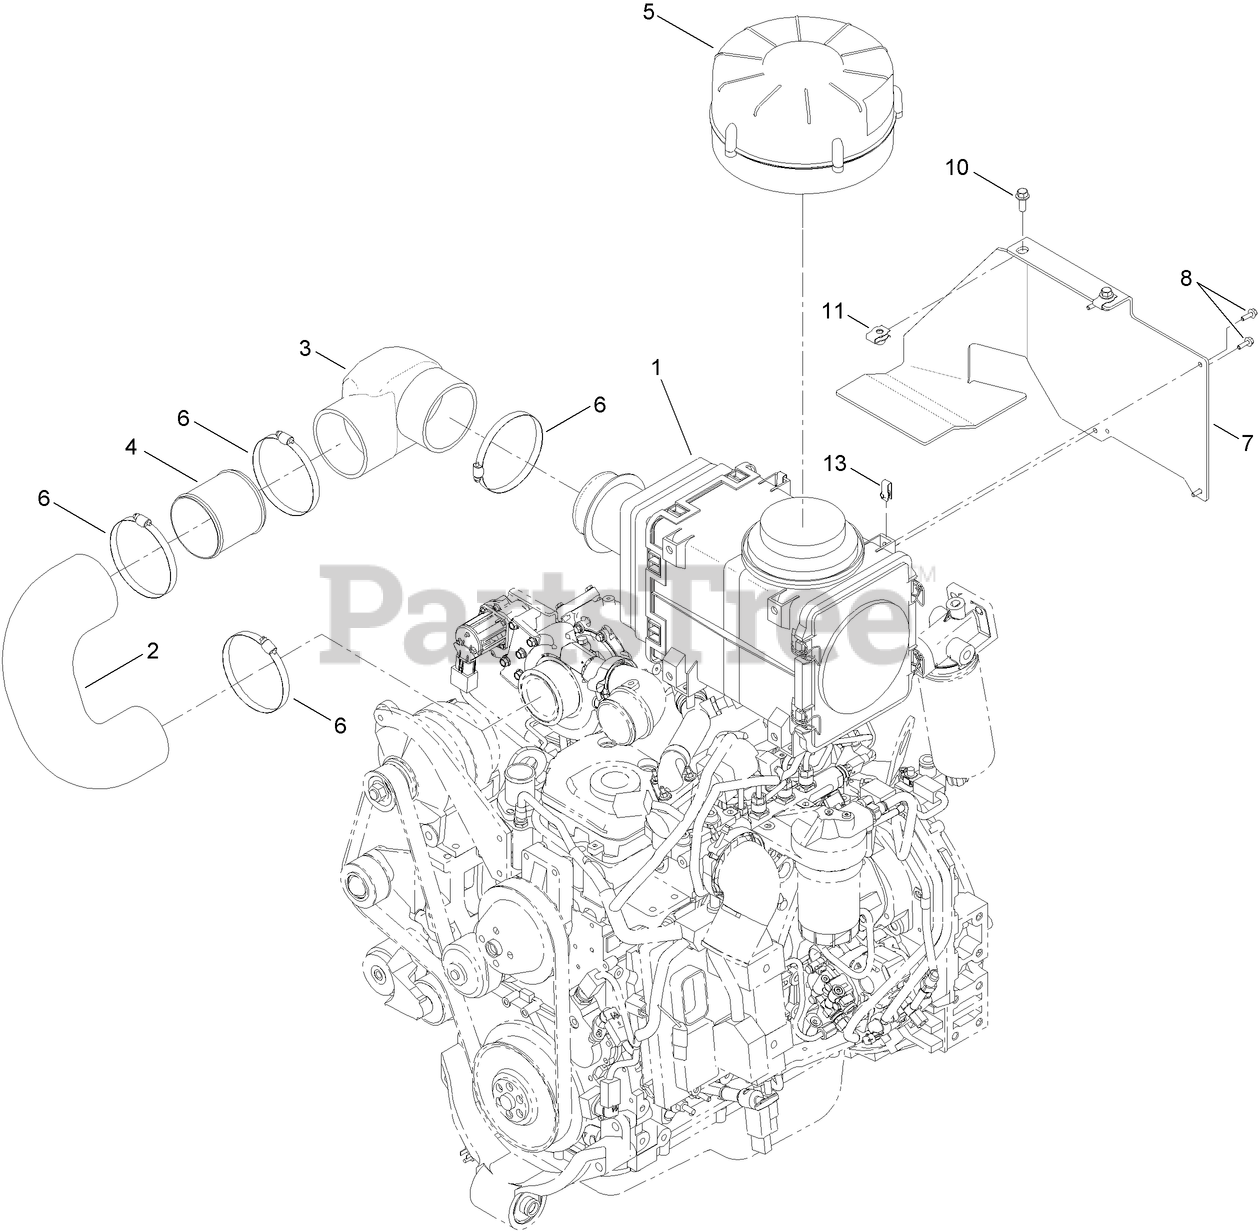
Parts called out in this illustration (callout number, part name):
1	AIR CLEANER ASM
2	HOSE-INTAKE
3	ELBOW-INTAKE, AIR CLEANER
4	CONNECTOR-INTAKE, AIR
5	PRECLEANER-INTAKE, AIR
6	CLAMP-HOSE
7	MOUNT-BOX, AIR
8	SCREW-HHF
10	SCREW-HHF
11	NUT-CLIP, U
